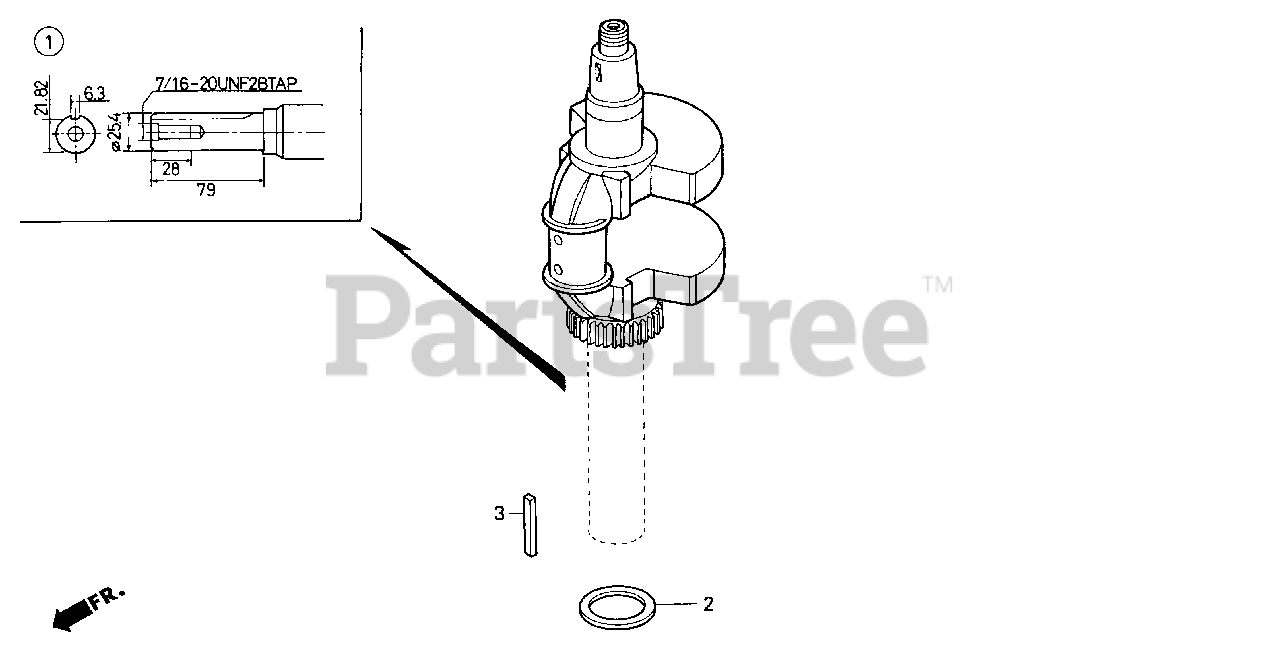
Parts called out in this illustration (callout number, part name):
1	CRANKSHAFT
2	WASHER, CRANKSHAFT THRUST
3	KEY (6.3X6.3X43)
